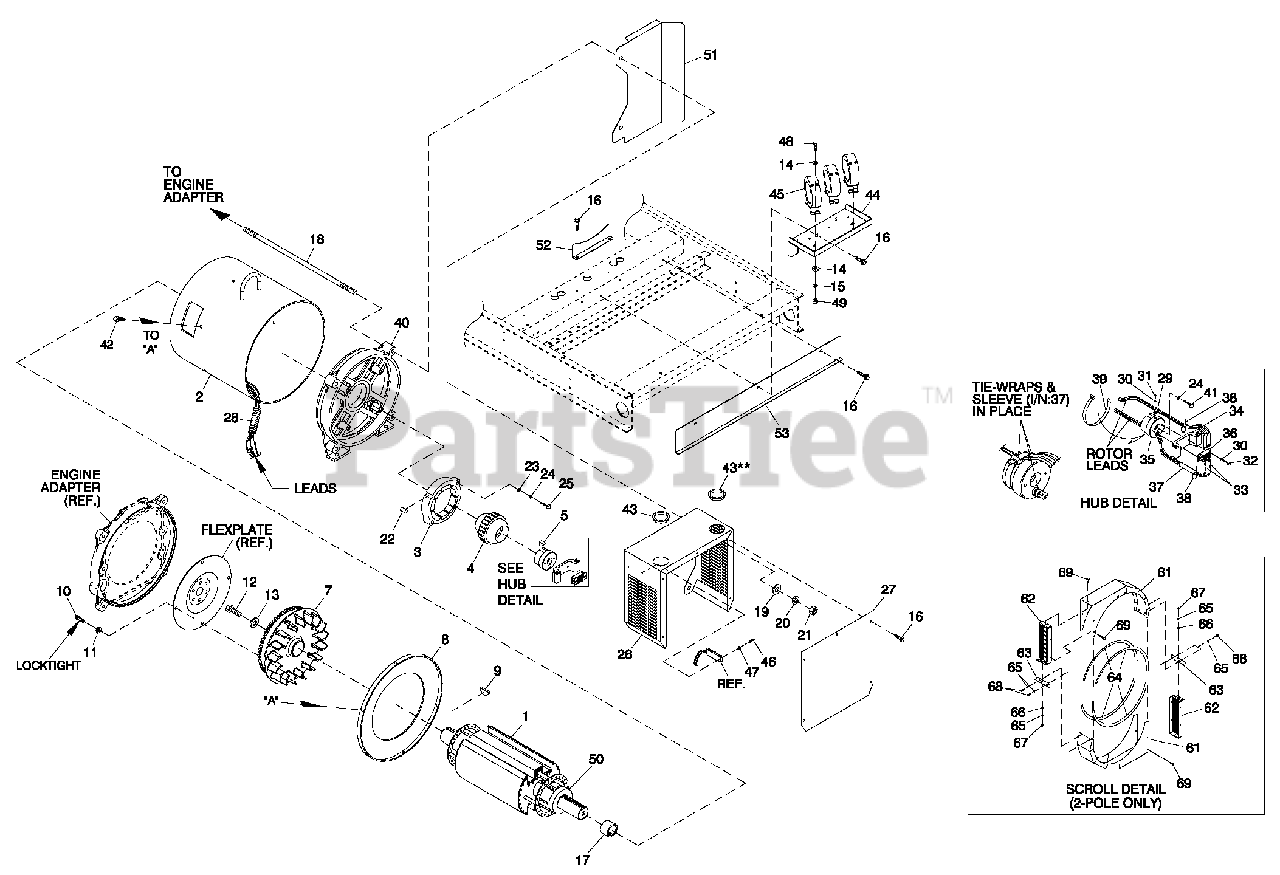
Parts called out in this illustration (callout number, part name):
1	ASSY ROTOR 2390 80KB3 CPL
2	ASSY STATOR 80KW 1PH 2P BRSHLS
3	EXITER FIELD 2" LG SPD CONN
4	ASSY EXCITER 2.0" STACK 2P
5	KEY SQ 3/8 X 3-1/4 STEEL
7	ASSY FLYWHEEL CPL
8	RING PRESSURE 390 STATOR CAN
9	KEY WOODRUFF #E
10	SCREW HHC M10-1.50 X 16 G10.9
11	WASHER LOCK M10
12	SCREW HHC M16-2.0X45G8.8
13	WASHER FLAT .688 ID X 3.25 OD
14	WASHER FLAT 1/4-M6 ZINC
15	WASHER LOCK M6-1/4
16	SCREW THF M6-1 X 16 N WA Z/JS
17	COLLAR SLIP FIT 390 MM
18	STUD M14-2.0X 760 G5 ZINC
19	WASHER FLAT M14
20	WASHER LOCK M14
21	NUT HEX M14-2.0G8YEL CHR
22	PIN DOWEL 1/2X 1-1/4
23	WASHER FLAT M12
24	WASHER LOCK M12
25	SCREW HHC M12-1.75X80 G10.9
26	SHIELD ALT EXCITER 390
27	COVER EXCITER SHIELD
28	CONDUIT FLEX 1.25" ID
29	CLAMP VINYL .312 X .203 Z
30	WASHER SHAKEPROOF INT #8
31	SCREW HHM #8-32X3/8
32	SCREW HHM #8-32X7/8
33	LUG RT-ANG #10/10-12
34	BRIDGE SUPPORT DIODE 15"
35	CAP END ROTOR 390MM
36	ASSY BRIDGE RECTIFIER
37	SLEEVING UL#0 .330 ID (3" LG)
38	TIE WRAP UL 3.9" X .10" BLK
39	TIE WRAP UL 17.7 X .35 BLK HT
40	CARRIER REAR BRG 15" (BRUSHLESS)
41	SCREW HHC M12-1.75X60 G10.9
42	SCREW 1/4-20 X 5/8" TAPTITE SS
43	BUSHING SNAP SB-2.5-31
44	MOUNT CT'S 5.4L100KW
45	TRANSFORMER
46	SCREW PHTT #6-32X1/2 ZYC
47	WASHER LOCK #6
48	SCREW HHC M6-1.0X 20 G8.8
49	NUT HEX M6 X 1.0 G8 YEL CHR
50	BEARING BALL 6212 SEALED
51	SHROUD UPPER ALTERNATOR EXCITR
52	SHROUD CENTER ALTERNATR EXCITR
53	SHROUD LOWERALTERNATOR EXCITR
60	ASSY SCROLL 390 X 60MM CPL
61	SHROUD ALT SHEET METAL CPL 2P
62	SCREEN, 390 SAE ALT 60MM WIDE
63	BRACKET SAE SCROLL TENSIONER
64	VINYL TRIM 1/8" GAP
65	WASHER, SPLIT 1/4" -M6
66	WASHER FLAT 1/4ZINC
67	SCREW HHC M6-1.0 x2 5 LONG
68	SCREW HHC M6-1.0X16G8.8
69	SCREW SWAGE 1/4-20 X 1/2 Z/YC
